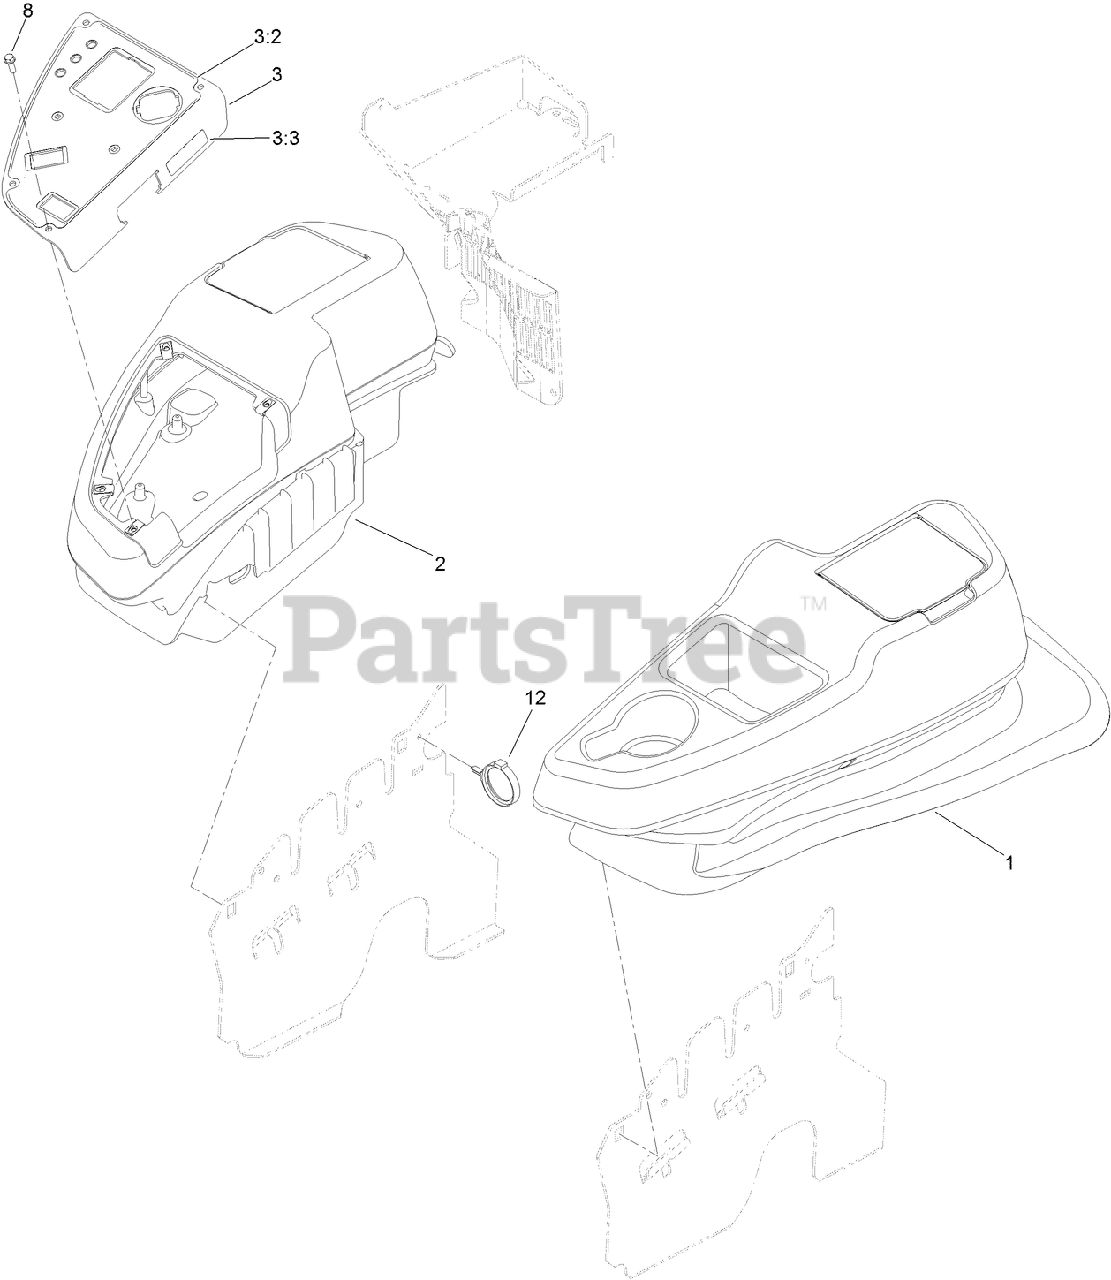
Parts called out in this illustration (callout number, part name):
1	LH CONSOLE ASM
2	RH CONSOLE ASM
3	CONTROL PANEL W/DECAL ASM
3:2	DECAL- PANEL, CONTROL
3:3	DECAL-FUSES
8	SCREW-HWH
12	CLAMP-HARNESS
